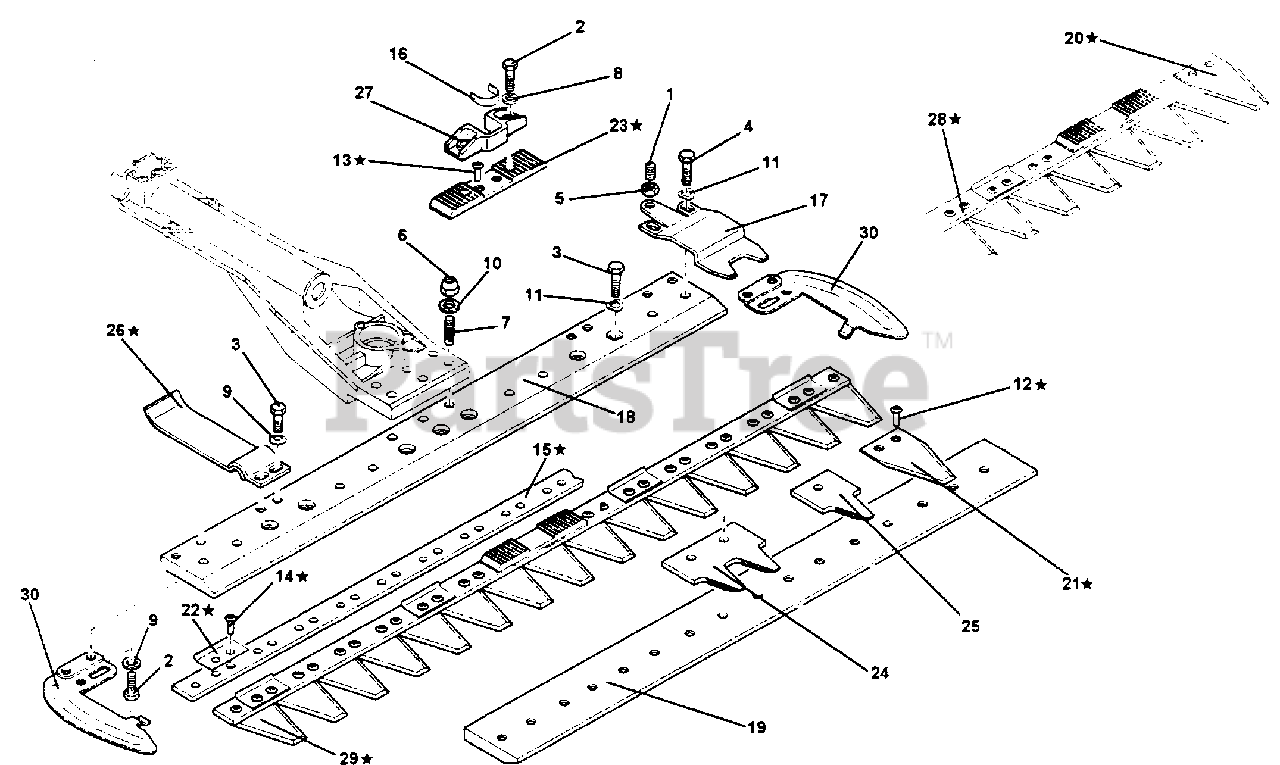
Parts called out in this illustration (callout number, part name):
1	SCREW M8X14
2	SCREW M8X16
3	SCREW M8X25
4	SCREW M8X35
6	NUT, LOCKING
8	WASHER FLAT 8.4
9	SUPER WASHER M8
10	SUPER WASHER M10
11	WASHER LOCK 8.4
12	RIVET 5.3X14
13	RIVET 5.3X18
14	RIVET 5.3X16
15	BLADE STRIP
17	BLADE HOLDER
18	CENTRAL BAR
20	SERATED BLADE
21	SMOOTH BLADE NLA USE REF #20
22	PLATE FOR CLEANING
23	BLADE COUPLING PLATE
24	DOUBLE FINGER
25	SINGLE FINGER
26	SLIDE WITH SCREWS
27	BLADE COUPLING PLATE
28	SERRATED BLADE ASSEMBLY
29	SMOOTH BLADE ASSEMBLY NLA USE REF #28
30	END GUARD, PAIR
